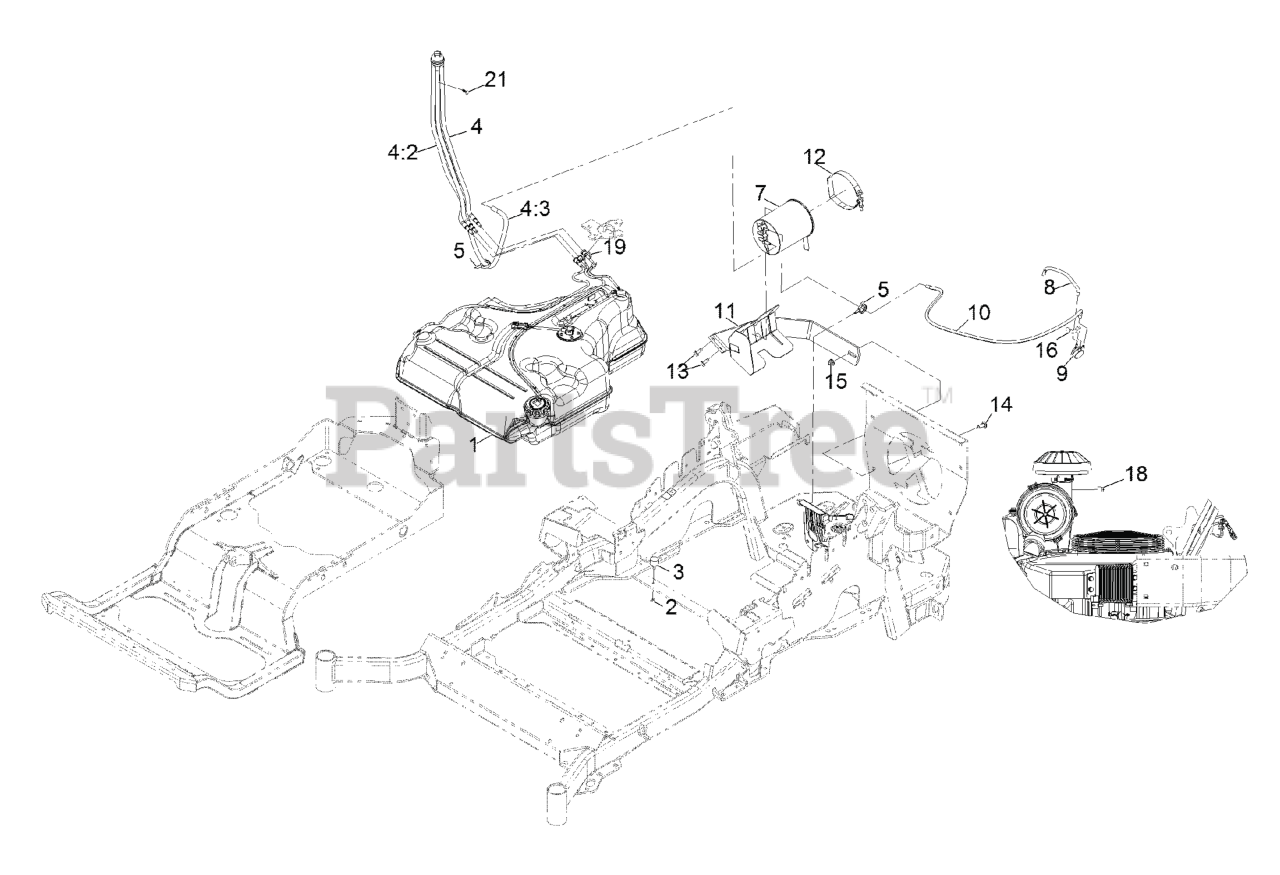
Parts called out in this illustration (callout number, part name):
1	FUEL TANK ASM
2	NUT-JAM
4	FUEL MANIFOLD VENT ASM
4:2	HOSE-FUEL
4:3	HOSE-FUEL
5	CLAMP-HOSE
7	CANISTER-CARBON, 1200CC
8	HOSE-VENT,FORMED
9	VALVE-CONTROL, VACUUM
10	HOSE,VENT,FORMED
11	MOUNT-CANISTER
12	CLAMP, T-BOLT
13	Screw-HWH 5/16-18 X 3/4 Tf
14	SCREW-CARR
15	NUT-HF, NI
16	HOSE-VENT, FORMED
18	PLUG-PORT
19	RETAINER-LINE, VAPOR
21	PLUG-PLASTIC
